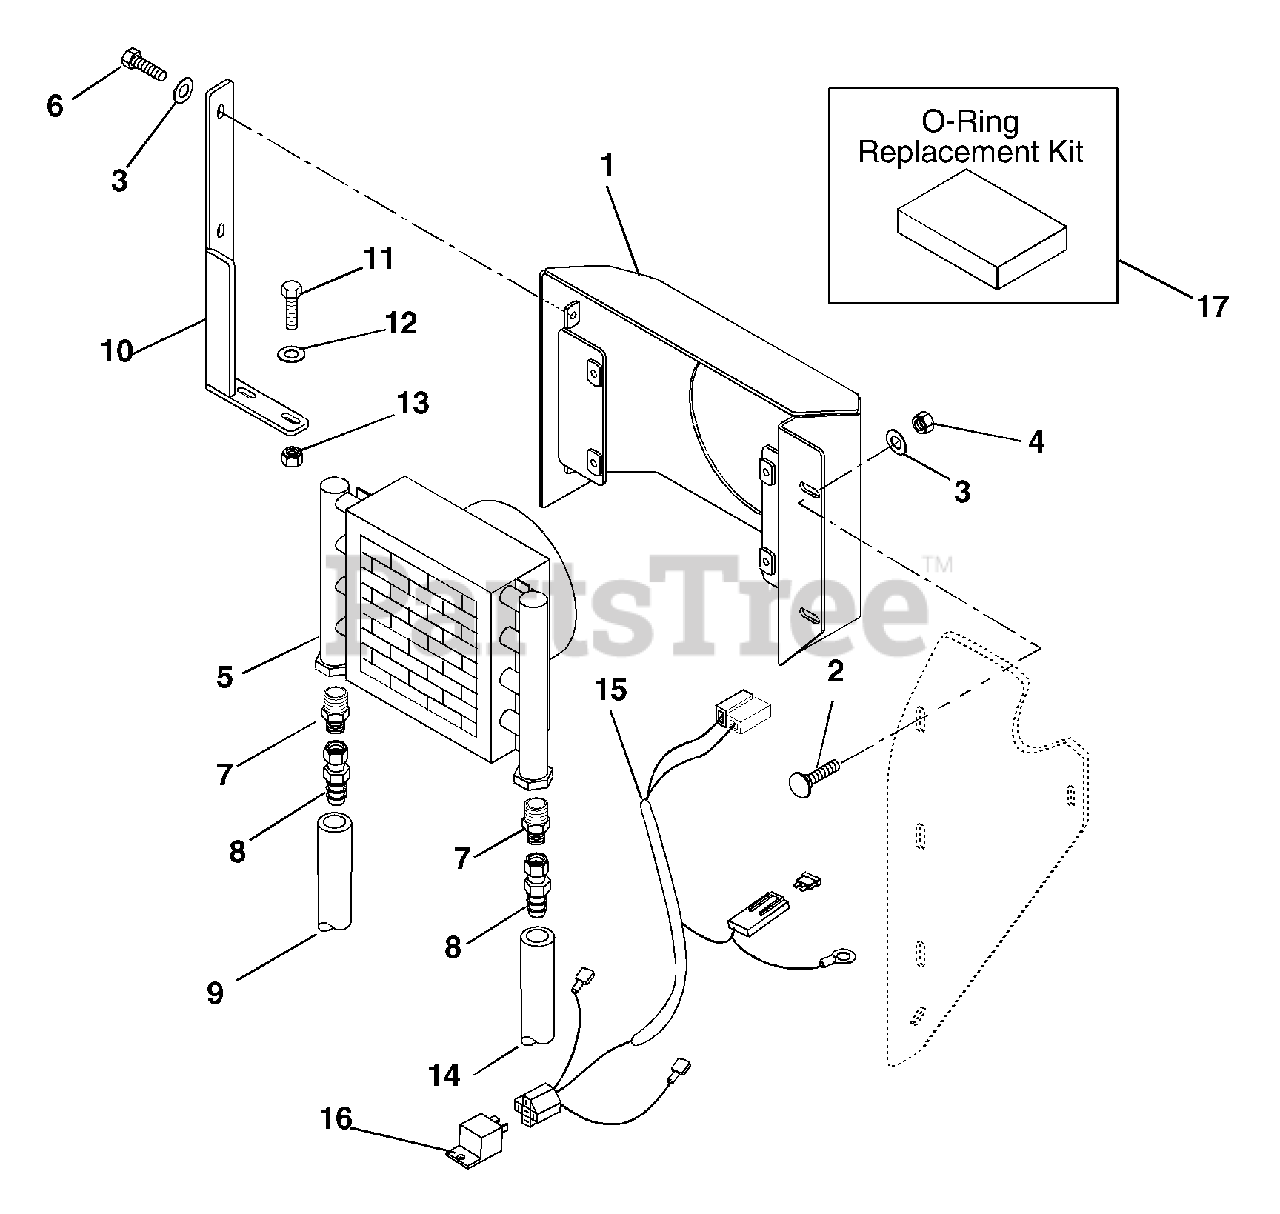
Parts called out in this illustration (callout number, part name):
1	Weldment, Cooler
2	Bolt-Round Head Square Neck M8-1.25 x 25
3	Washer-Flat-Steel .38 x .875 x .083
4	Nut-Locking-Nylon M8-1.25
5	Cooler, Hydraulic Oil
6	Bolt-Hex M8 x 1.25 x 25 Grade 8
7	Fitting, Hydraulic Straight
8	Fitting, Hydraulic Straight Swivel
9	Hose, Hydraulic
10	Bracket, Cooler Mounting-Diesel
11	Bolt-Hex M8 x 1.25 x 30 Grade 5
12	Washer-Flat-Steel .344 x .688 x .065
13	Nut-Locking-Nylon M8-1.25
14	Hose, Hydraulic
15	Harness, Wire- Cooler
16	Relay
17	Assorted O-Rings
